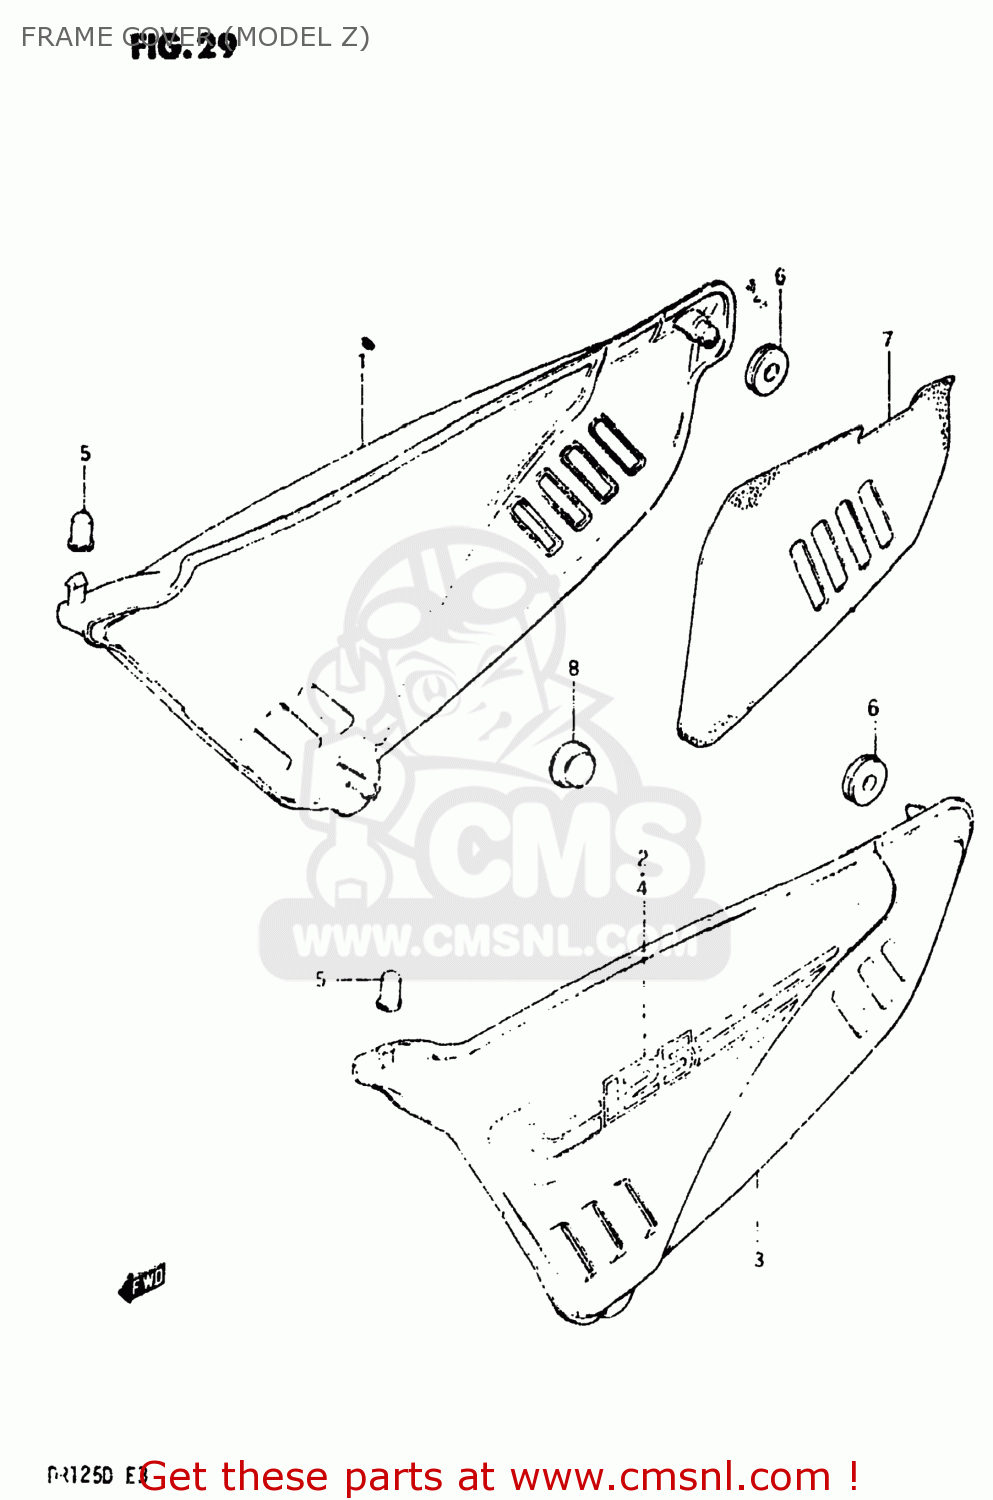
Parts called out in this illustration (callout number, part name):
1	COVER,FRAME,RIGHT
2	TAPE SET,FRAME COVER
3	COVER,FRAME,LEFT
4	TAPE SET,FRAME COVER,LEFT
5	CUSHION
6	CUSHION
7	HEAT SHIELD,FRAME COVER
8	CUSHION
